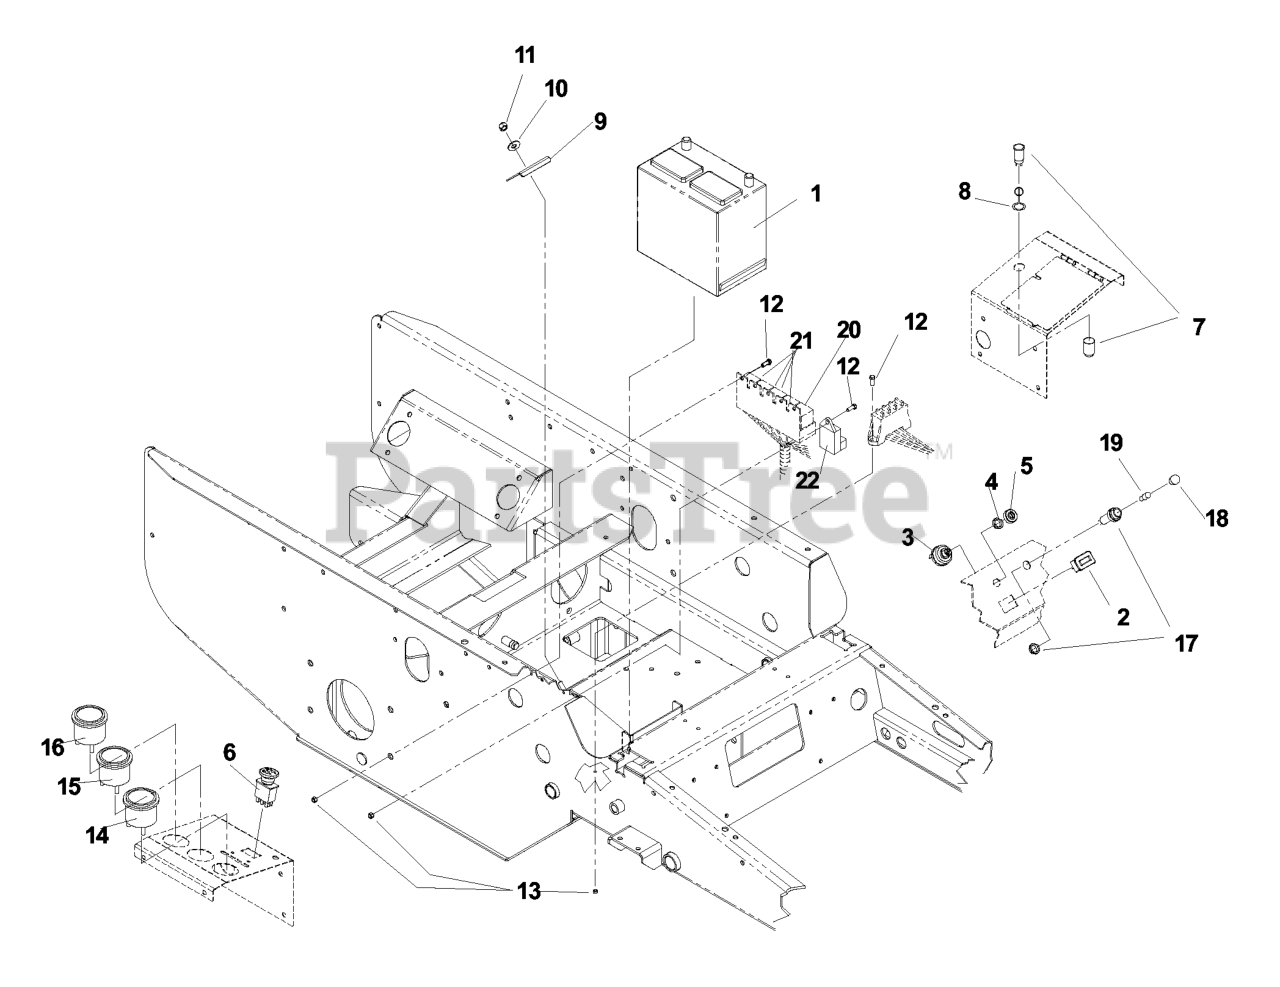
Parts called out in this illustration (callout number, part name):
2	DIGITAL HOUR METER
3	IGNITION SWITCH KIT
4	DNO IGNITION NUT
5	CAP IGNITION NUT
6	RP.SWITCH, BLADE
7	POWER SOURCING HSG
8	POWER SOURCE CAP
10	WASHER 5/16 FLAT
11	NUT 5/16 NYLOC
12	SCREW 10-24 X 3/4
13	NUT 10-24 NYLOC
14	TEMP GAUGE DATCON #100182
15	GAUGE, AMPMETER DATCON 100160
16	GAUGE, OIL PRES DATCON 100172
17	LAMP SPROCKET
22	TIMER/GLOW PLUG
